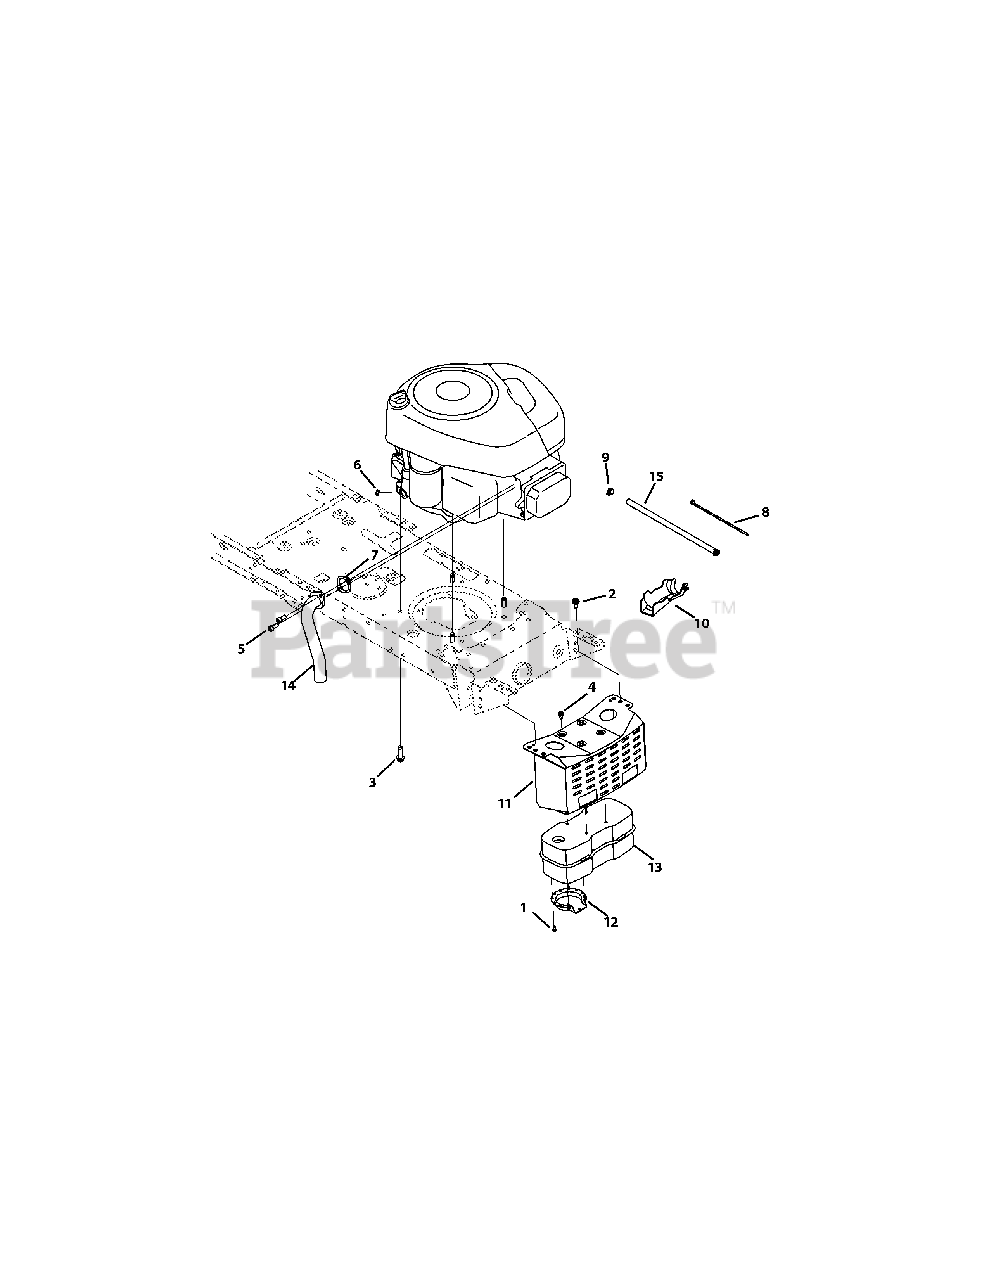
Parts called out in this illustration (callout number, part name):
1	Screw, 8-18 x .500
2	Screw, 5/16-18 x .750
3	Screw, 3/8-16 x 1.000
4	Screw, 1/4-20 x .500
5	Socket Screw, 5/16-18 x .750
6	Sems Nut, 1/4-20
7	Exhaust Gasket, 10 HP Briggs
8	Cable Tie
9	Hose Clamp, .490 Diameter
10	Oil Drain Sleeve
12	Muffler Deflector
13	Single Inlet Muffler
14	Exhaust Pipe, Single Briggs
15	Fuel Hose, Low Permeation
